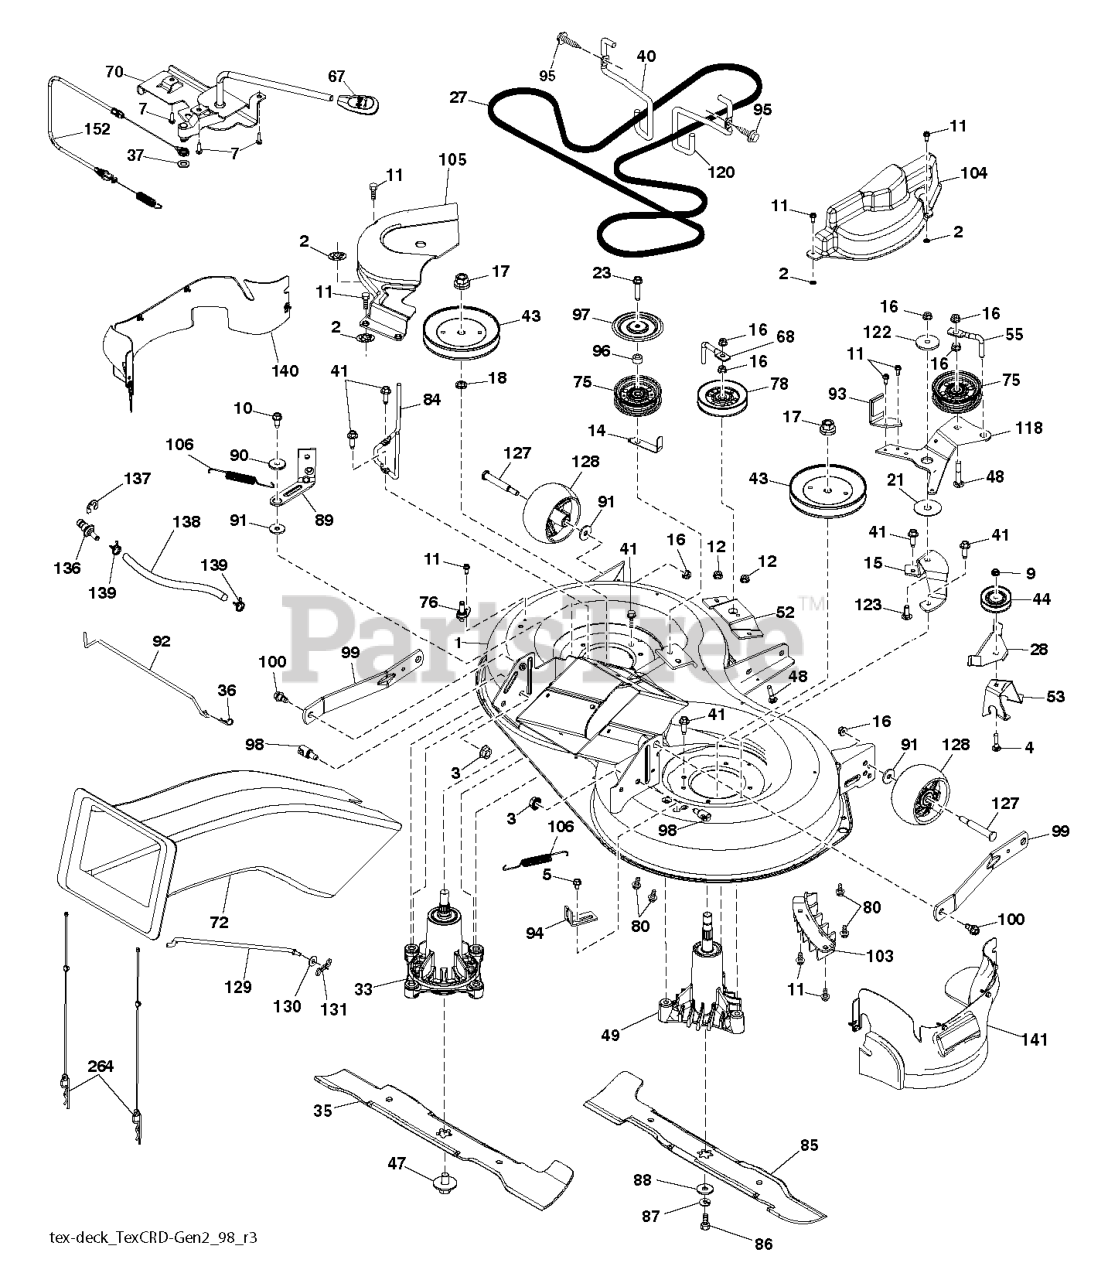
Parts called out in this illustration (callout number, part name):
1	KIT.SVC.DECK.WLD.97CM.TEX.498
2	PALNUT 1/4
3	GSPW Nuts
4	BOLT.CARRIAGE.5/16-18
5	BOLT.5/16HEX.WHS.HD
9	NUT HEX FLG NYLOCK BLK 5_16-1
10	SCREW 3/8-16X1
11	SCREW.1/4-20X5/8
12	NUT HEXAGON FLANGE 5/16-18 ST
14	KEEPER, BELT IDLER
15	BRACKET CRD IDLER ARM MOUNT BL
16	NUT LOCK FLG 3/8-16 UNC
18	WASHER.SPACER.MANDREL
23	BOLT;HEX_3/8-16 X 1.78.CLRZINC
28	KEEPER 97 CRD ANGLED IDLER KEE
33	KIT.MANDREL.NONGREASE.TALL
35	BLADE.3N1.LH.CRD.97
36	RETAINER M
37	WASHER PLAIN WASHER 3/8 X 0.08
40	KEEPER BELT ENGINE LH
41	BOLT.HEX.WASHR.HED.313-18X1.19
43	PULLEY.MANDREL.5.438.PD
44	PULLEY.V-IDLER.
47	SCREW.SEMS.7/16-20X1.HEX.HEAD
49	MANDREL ASM.CRD RH 6PT STAR
53	BRACKET 97 CRD ANGLED V-IDLER
67	HANDLE.CLUTCH.CABLE.LT
70	CLUTCH.ASM.MANUAL.YT.PREDATORQ
72	CHUTE.SLOTTED.HOLES.TEX.CRD.II
76	1/2" BARB.DECK.WASHOUT.PORT
78	REPL BY 532 1467-63
80	GSPW Bolts
84	KEEPER.BLT.PNT.MNDRL.PULL.6.25
85	BLADE.3N1.RH.CRD.97
86	BOLT.3/8-24X1.25GR8. LHTHRD
88	WASHER.BLADE
89	ARM.BRAKE.97.LH
90	SPACER.RETAINER
92	LINK 97 CRD MANUAL DRIVE BRAKE
93	BRAKE CRD RH BRAKE ARM BLACK E
94	BRKT.CLUTCH.CABLE
95	SCREW, 3/8-16X3/4
96	SPACER
97	PROTECTOR
98	STUD.W/"D"ANTI-ROTATION
99	ARM.SUSPENSION.MOWER.R
100	BOLT.SHOULDER
103	GUARD GUARD FRONT VENT
104	GUARD 97CRD RH MANDREL COVER;
105	MANDREL MANDREL COVER LH
106	SPRING.BRAKE.RETURN.38"
120	KEEPER BELT RH
122	SPACER.RETAINER.MOWER
128	WHEEL.GAUGE.RALLY
129	ROD ROD. SWAY CRD GEN II
131	PIN.COTTER.5/16.BOW TI
136	PLUG WASHOUT PORT HOOKUP
138	HOSE.3/8ID.BULK.12"
140	GUARD.ASSEMBLY.97.LH.FRENCH
141	GUARD.ASSEMBLY.97.RH.FRENCH
152	CABLE CABLE CLUTCH MANUAL W/S
